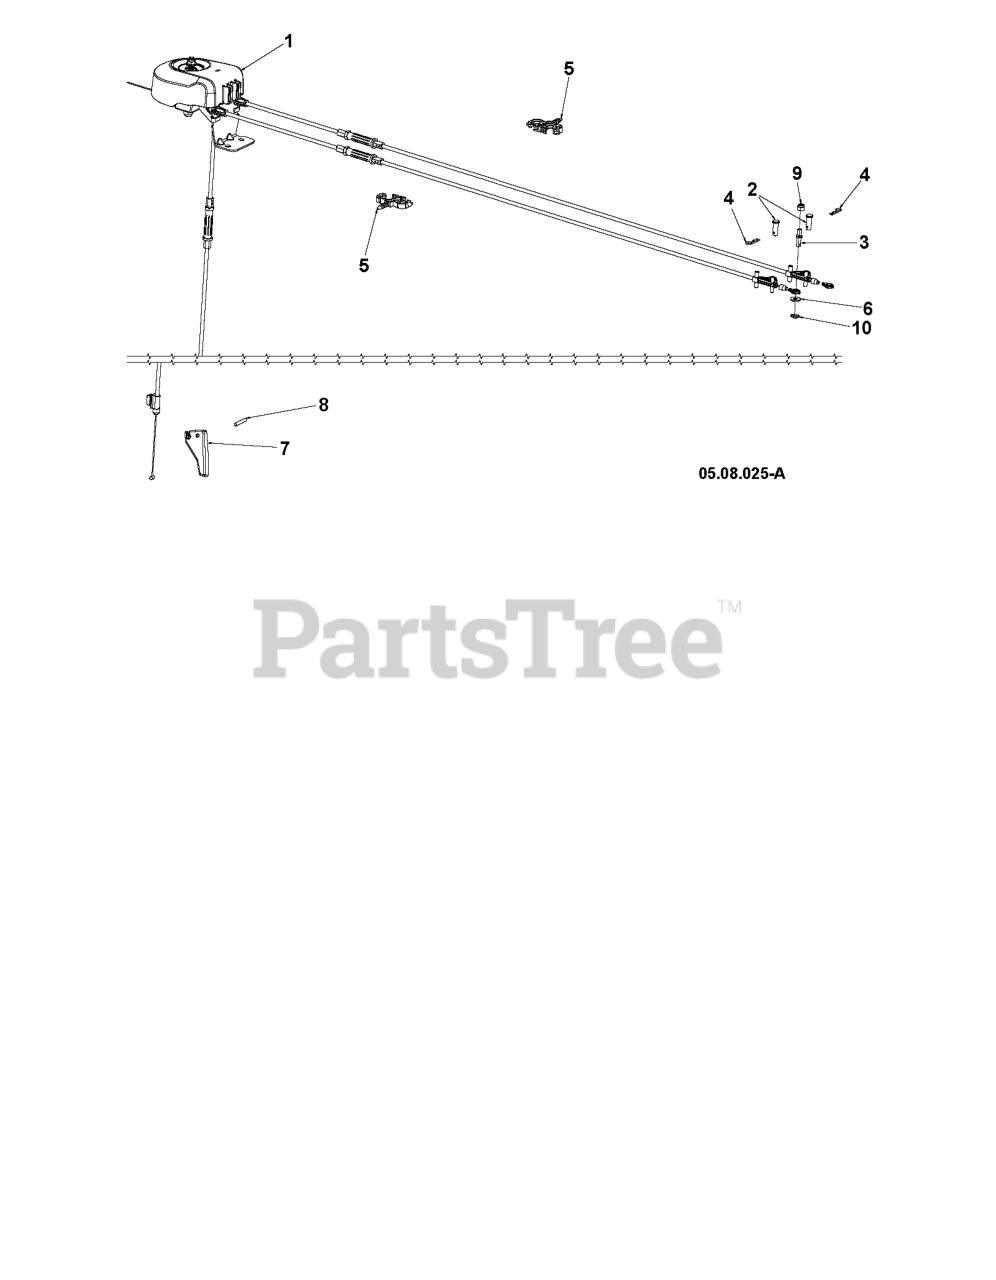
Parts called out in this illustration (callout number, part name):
1	CABLE CHUTE ROTATOR ASM LOCKIN
2	PIN CLEVIS 5/16X.875
4	HAIRPIN.SOFT.ZINC.059X1.125
5	CLIP.CONDUIT.DOUBLE LOOP
6	WASHER FLAT_.250 X .625 X .06
8	PIN, ROLL 3/16 X 1-1/8
9	NUT HEXAGON 1/4-20 ST ZPB
10	GSPW Retainers
